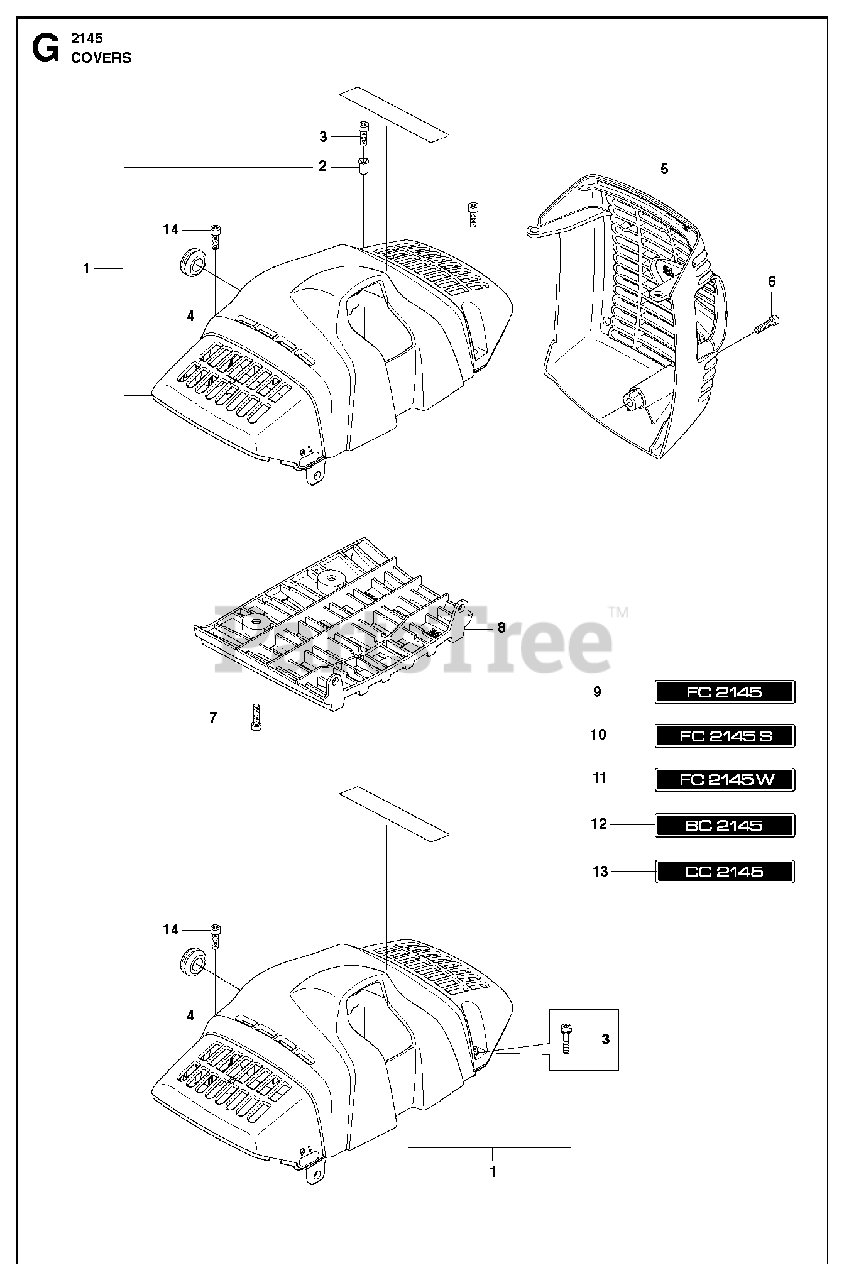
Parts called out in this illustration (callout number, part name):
1	CYLINDER COVER ASSY
3	SCREW IHSCFM
3	SCREW IHSCFMO
5	MUFFLER COVER
6	SCREW IHSCFM
7	SCREW IHSCFM
9	DECAL
10	DECAL
12	DECAL
